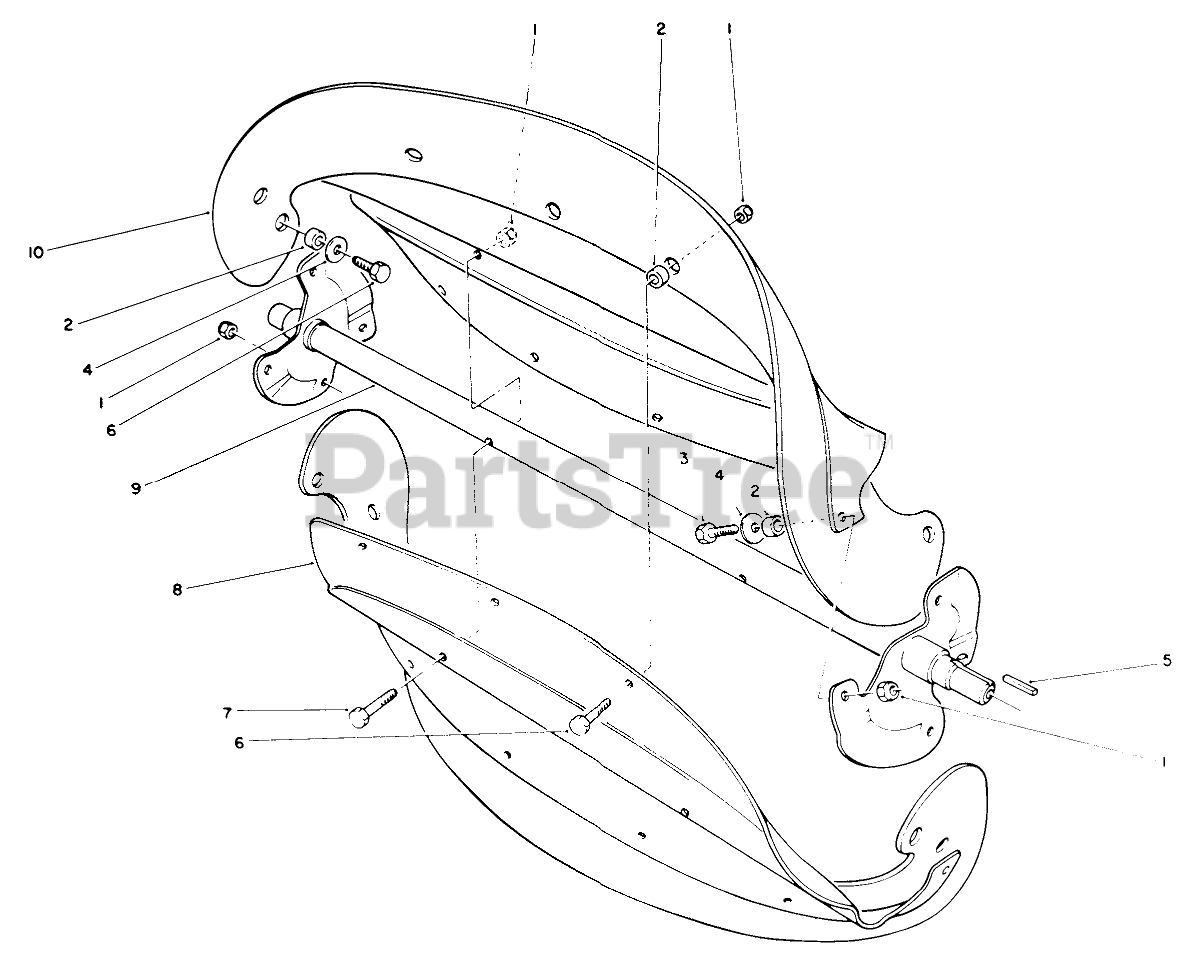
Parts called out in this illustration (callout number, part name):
1	NUT-LOCK, NI
2	SPACER-BLADE, ROTOR
3	SCREW-HH
4	WASHER-FLAT
5	KEY-SQUARE
6	SCREW-HH
7	SCREW-HH
8	ROTOR
9	ROTOR WA
10	Blade-Rotor
